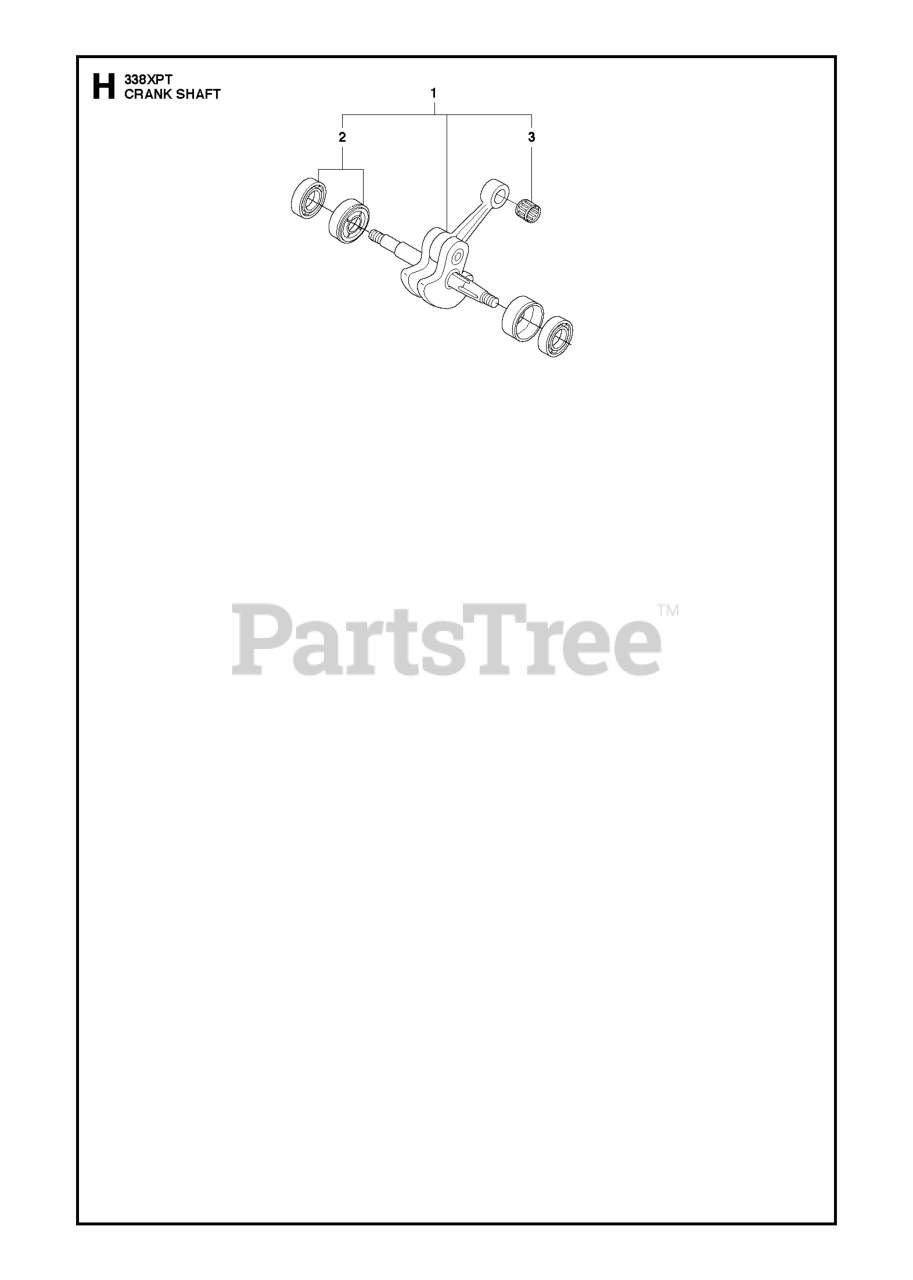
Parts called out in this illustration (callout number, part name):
1	CRANKSHAFT
2	HOLDER BALL BEARING
3	SUPPORT BUSHING
